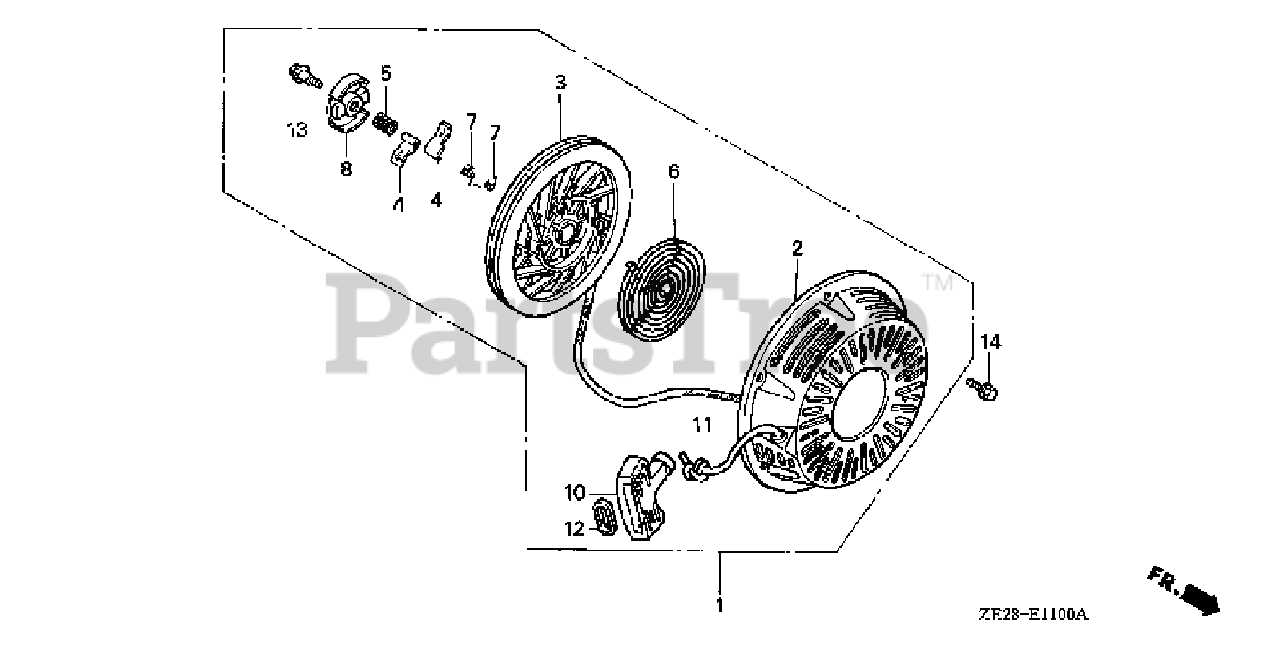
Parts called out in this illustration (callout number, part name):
1	STARTER ASSY., RECOIL *R8* (BRIGHT RED)
2	CASE, RECOIL STARTER *R8* (BRIGHT RED)
3	PULLEY, RECOIL STARTER
4	RATCHET, STARTER
5	SPRING, FRICTION
6	SPRING, STARTER RETURN
7	SPRING, RATCHET
8	RETAINER, SPRING
10	GRIP, STARTER
11	ROPE, RECOIL STARTER (NA USE ALT:08550-ZG921-11)
12	GRIP, REINFORCEMENT
13	SCREW, CENTER
14	BOLT, FLANGE (6X8)
